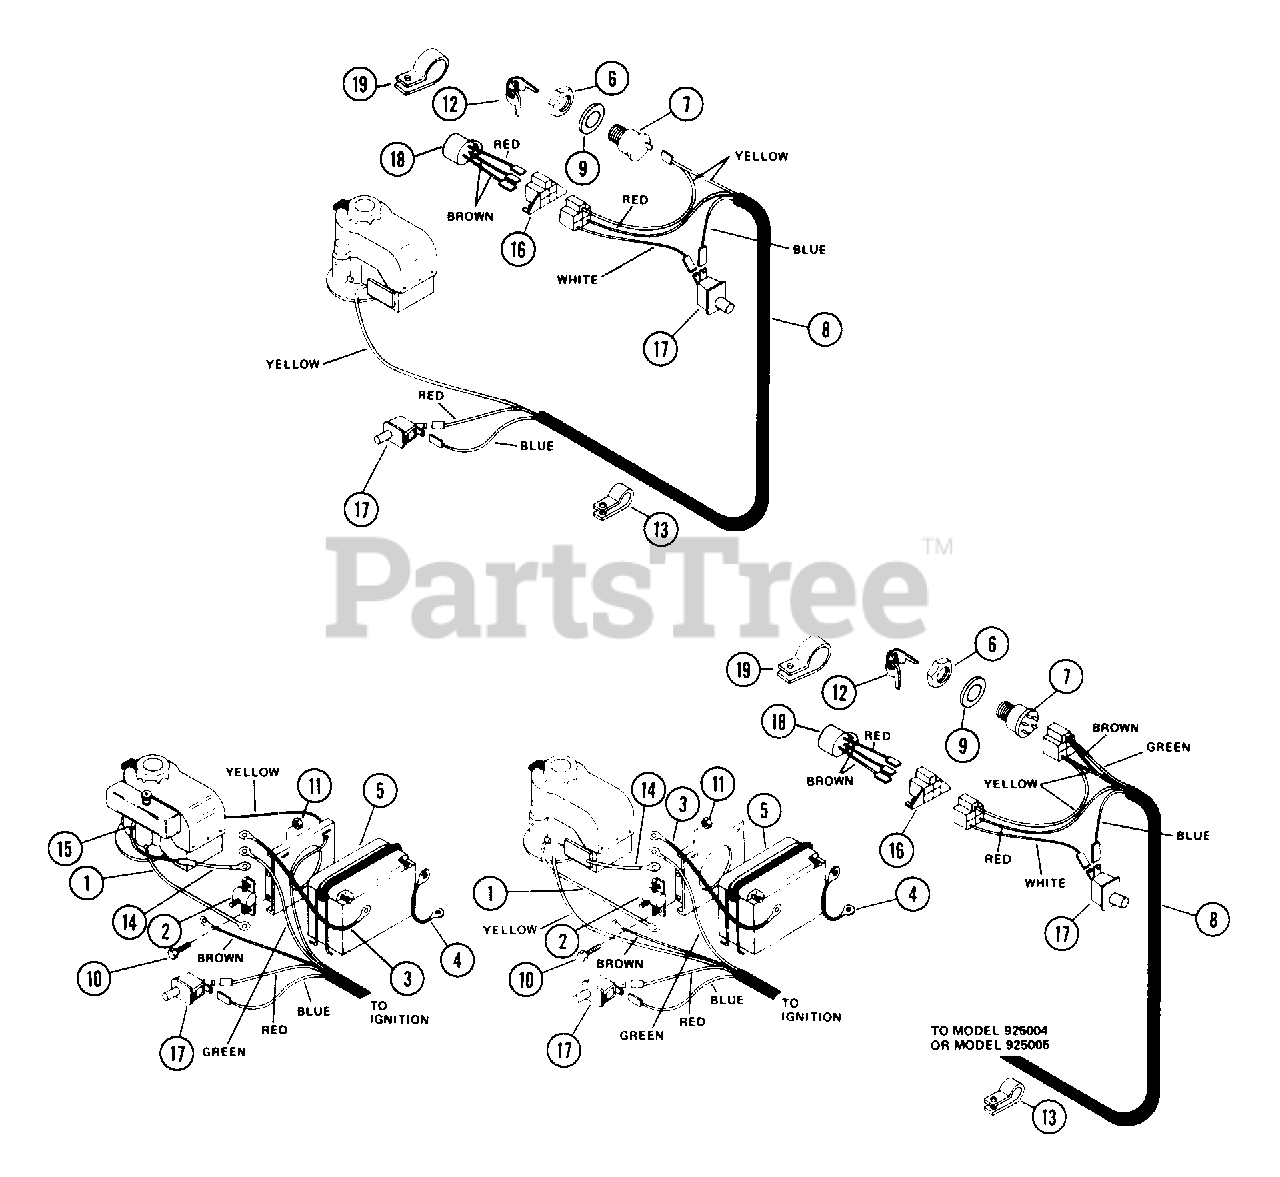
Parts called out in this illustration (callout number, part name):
1	GROUND CABLE
1	GROUND CABLE .25X13.00X.31
2	SOLENOID
3	BATTERY CABLE
4	GROUND WIRE
5	BATTERY
6	NUT .625-32 ALUM
7	IGNITION SWITCH ASSEMBLY
8	WIRING HARNESS
9	WSHR-LK-INT .625X.045 PL
10	BLT-HEX .25-20X.50 PL GR2
11	NUT-LK-CTR .250-20 PL
12	KEYS
13	CLIP
14	CHARGING WIRE
15	FUSE
16	CONNECTOR
18	MODULE T
